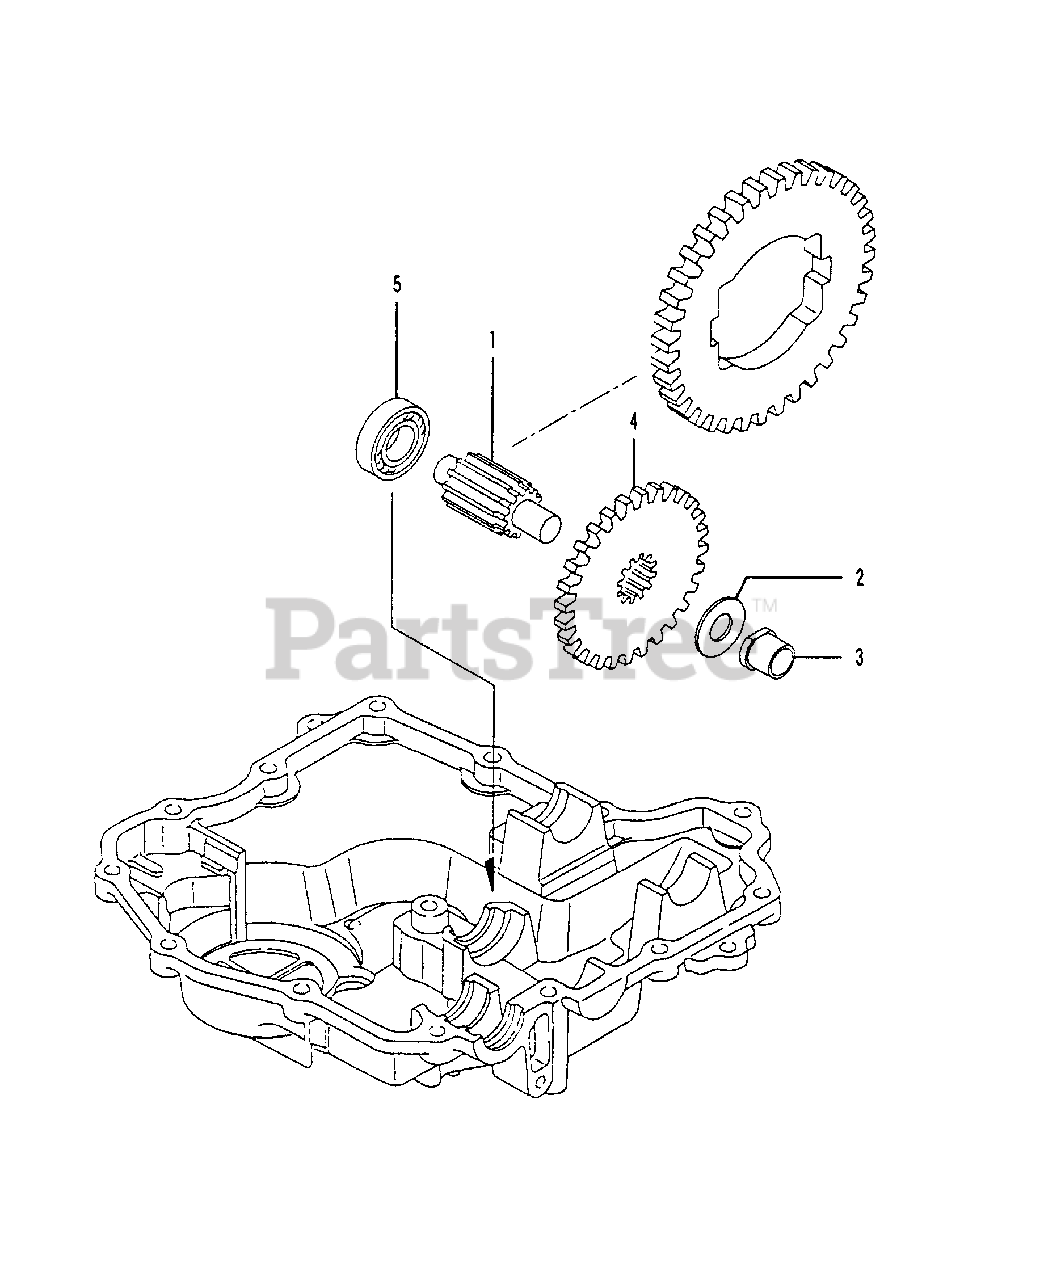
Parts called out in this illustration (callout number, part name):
1	SHAFT (FINAL PINION
2	WASHER 15 X 32 X 1
4	GEAR 51 (FINAL SHAFT
5	BEARING 6203
